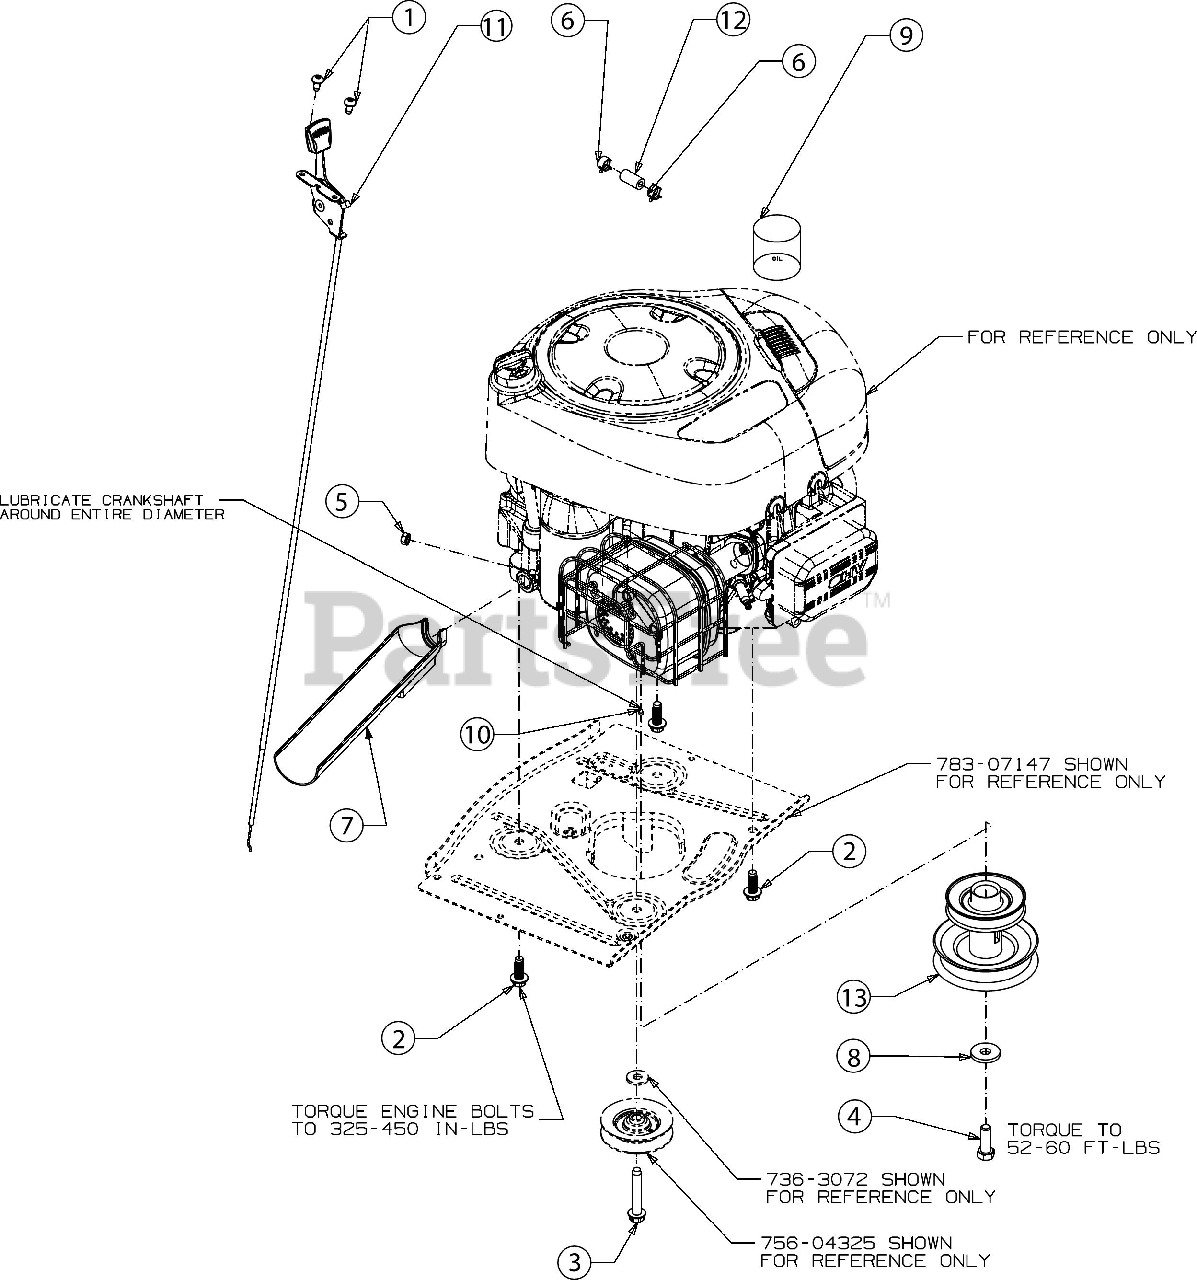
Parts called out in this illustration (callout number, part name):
1	SCREW 1/4-20 x .500
2	SCREW 3/8-16 x 1
3	SCREW 3/8-16 x 2.250
4	SCREW 7/16-20 x 1.250 GR5
5	SEMS NUT 1/4-20
6	HOSE CLAMP 1/20
8	FLAT WASHER .445 x 1.248 x .170
9	OIL 10W30 (NOT SERVICEABLE)
10	GREASE (NOT SERVICEABLE)
11	THROTTLE CABLE 31" x 1.1
12	FUEL HOSE LOW PERMEATION
13	ENGINE PULLEY
